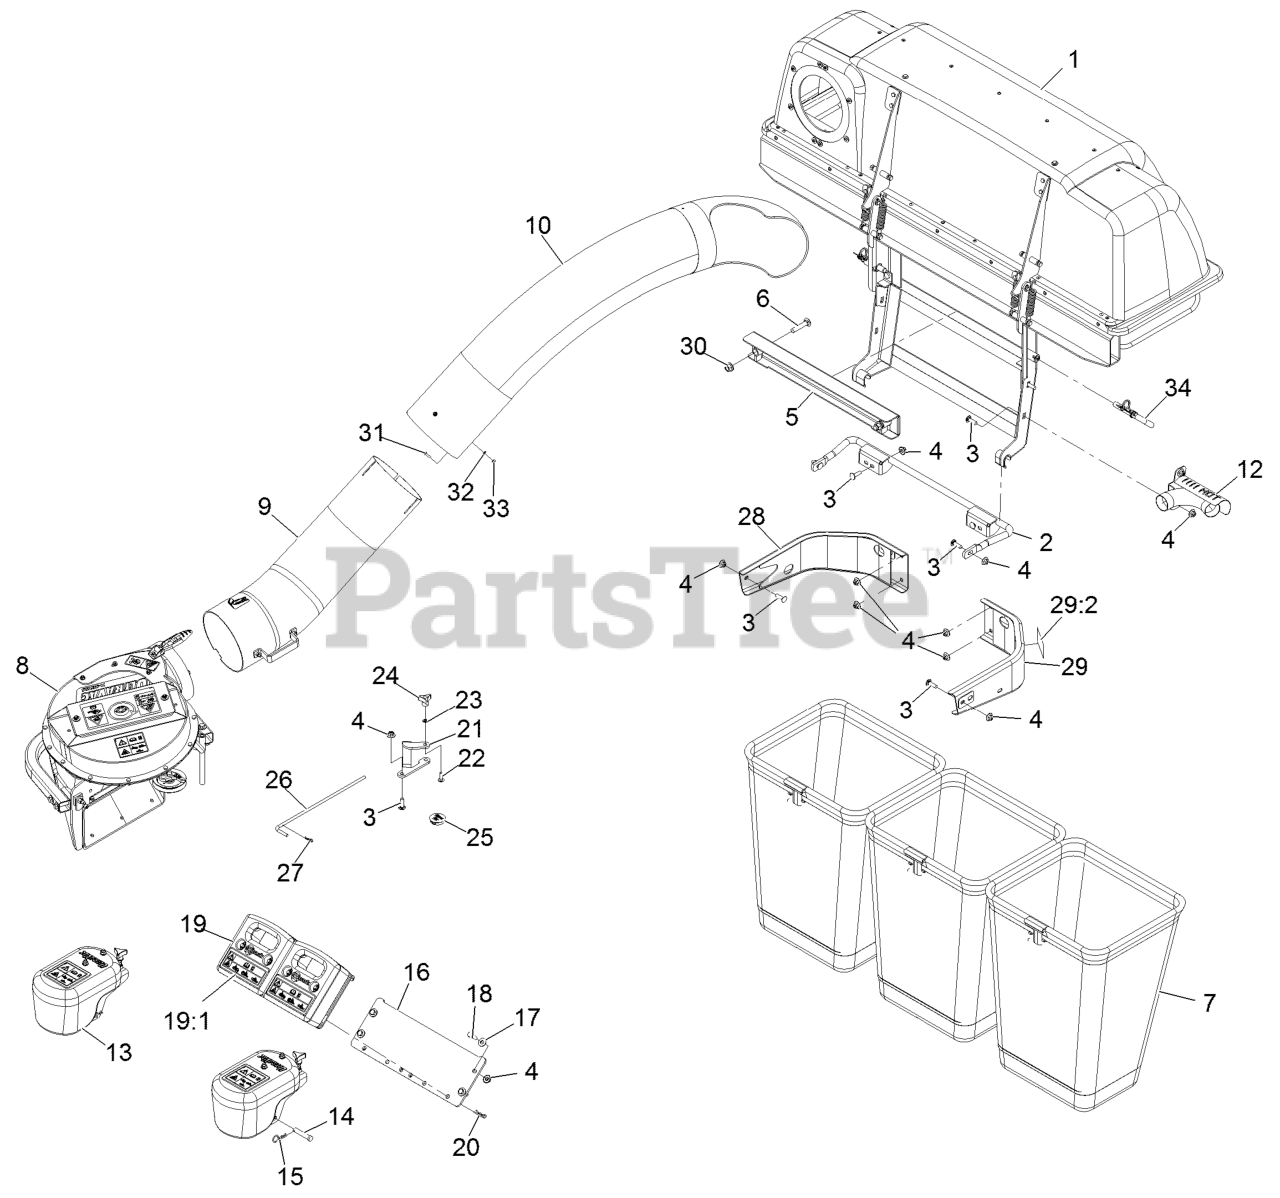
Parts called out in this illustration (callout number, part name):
1	ASM,Hood Uv 3 Bag
2	MOUNT-BAGGER, LOWER
3	Bolt-Carriage 3/8-16 X 1 1/4
4	Nut-Nyloc 3/8-16 Flg
5	MOUNT-BAGGER, UPPER
6	SCREW-CARR
7	BAG AND FRAME ASM
8	ASM, BLOWER LARGE - SVC O
9	LOWER TUBE ASM
10	TUBE-UPPER
12	EXHAUST DIVERTER ASM
13	ASM,CASTER WEIGHT
14	PIN-CLEVIS
15	PIN-COTTER
16	PLATE,WEIGHT ASM MOUNT
17	WASHER-FLAT
18	SCREW-HH
19	ASM,CAST WEIGHT
19:1	DECAL-WARNING WEIGHT
20	PIN-HAIR
21	BRACKET,BELT COVER
22	BOLT-CARR
23	RING-RETAINING, BOLT
24	KNOB-3 PRONG
25	PLUG, BLACK NYLON 1.75
26	PIN,CHUTE PIVOT
27	PIN-COTTER
28	BUMPER-RH
29	LH BUMPER ASM
29:2	DECAL-WARNING
30	Nut-Lock 1/2-13
31	SCREW-HWH
32	WASHER-FLAT
33	NUT-LOCK, NI
34	PIN-MOUNT, BAGGER
